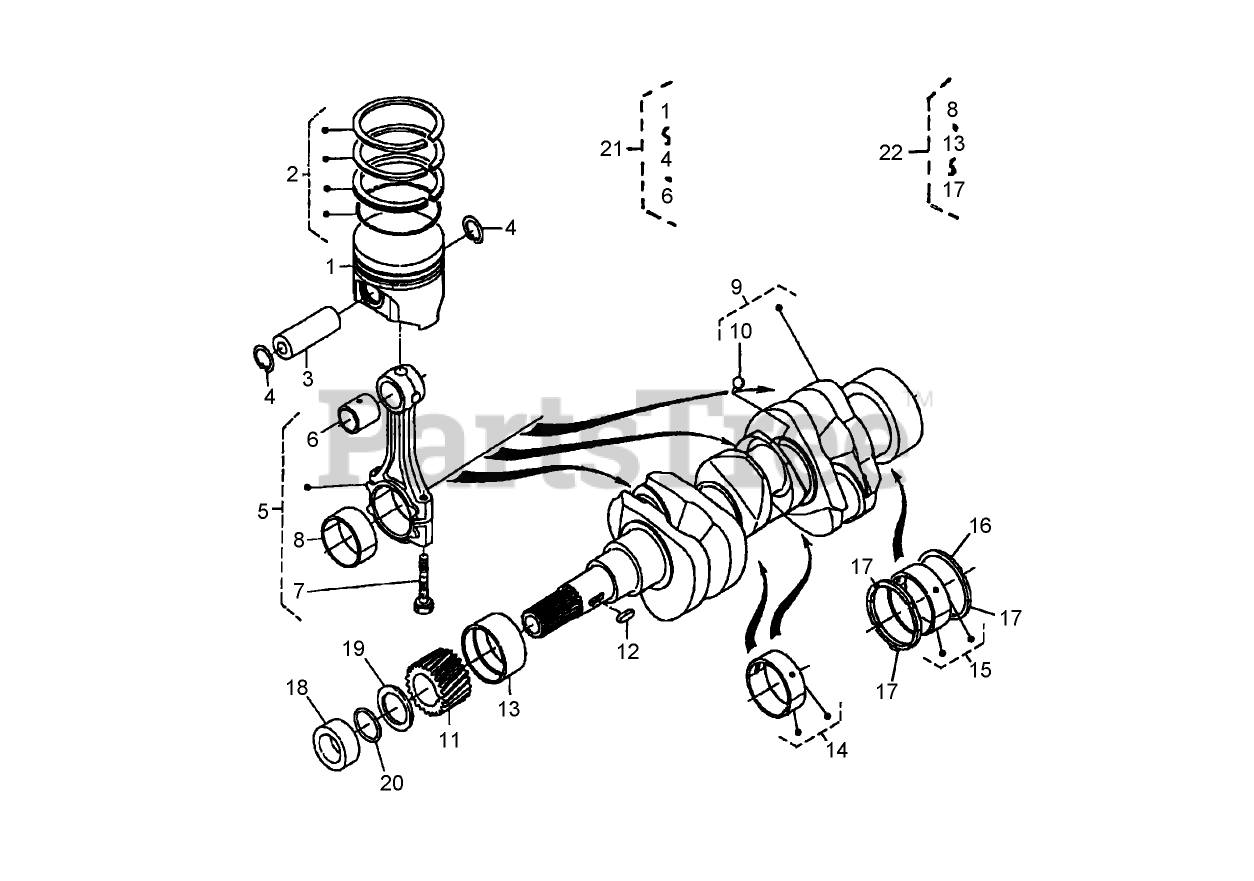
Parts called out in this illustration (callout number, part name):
1	PISTON
2	PISTON RING ASM (STD)
2	PISTON RING ASM (+.25MM)
3	PIN-PISTON
4	CIRCLIP-INTERNAL
5	CONNECTING ROD ASM
6	BUSHING-PIN, PISTON
7	BOLT-ROD, CONNECTING
8	METAL-CRANKPIN (-0.20mm)
8	METAL-CRANKPIN (-0.40mm)
8	METAL-CRANKPIN (STD)
9	CRANKSHAFT
11	GEAR-CRANKSHAFT
12	KEY-FEATHER
13	METAL-CRANKSHAFT (STD)
13	METAL-CRANKSHAFT (-.0.20MM)
13	METAL-CRANKSHAFT (-0.40MM)
14	CRANKSHAFT METAL ASM (STD)
14	CRANKSHAFT METAL ASM (-0.20MM)
14	CRANKSHAFT METAL ASM (-0.40mm)
15	CRANKSHAFT METAL ASM (STD)
15	CRANKSHAFT METAL ASM (-0.20MM)
15	CRANKSHAFT METAL ASM (-0.40MM)
16	METAL-SIDE (STD)
16	METAL-SIDE (+0.20MM)
16	METAL-SIDE (+0.40MM)
17	METAL-SIDE (STD)
17	METAL-SIDE (+0.2MM)
17	METAL-SIDE (+0.4MM)
18	COLLAR-CRANKSHAFT
19	SLINGER-OIL
20	O-RING
21	PISTON KIT (STD)
21	PISTON KIT
22	ENGINE METAL KIT
